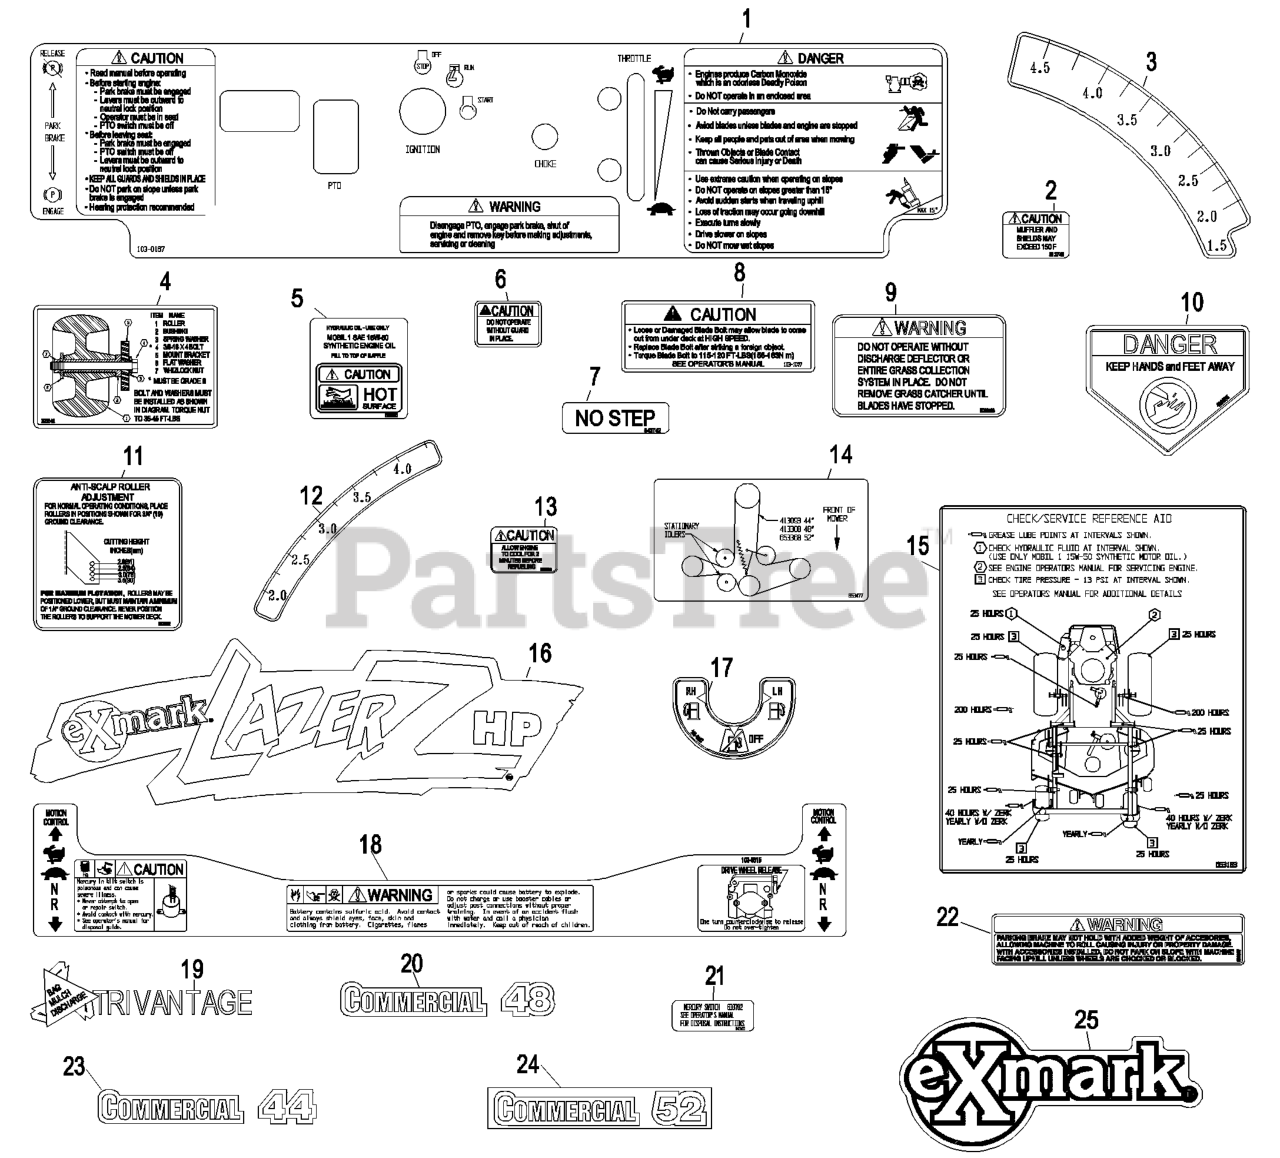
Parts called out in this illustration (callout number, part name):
3	DECAL-DECK HEIGHT, OUTER
4	DECAL,ROLLER MOUNTING
6	DECAL-GUARD
7	DECAL,NO STEP
8	Decal, Bolt Torque
9	DECAL-WARNING, DISCHARGE
10	DECAL-DANGER
11	DECAL,ANTISCALP
12	DECAL-DECK HEIGHT, INNER
17	DECAL-VALVE, FUEL
20	DECAL,COMMERCIAL 48
21	DECAL-SWITCH, MERCURY
22	DECAL,PARK BRAKE WARNING
23	DECAL,COMMERCIAL 44
24	DECAL,COMMERCIAL 52
